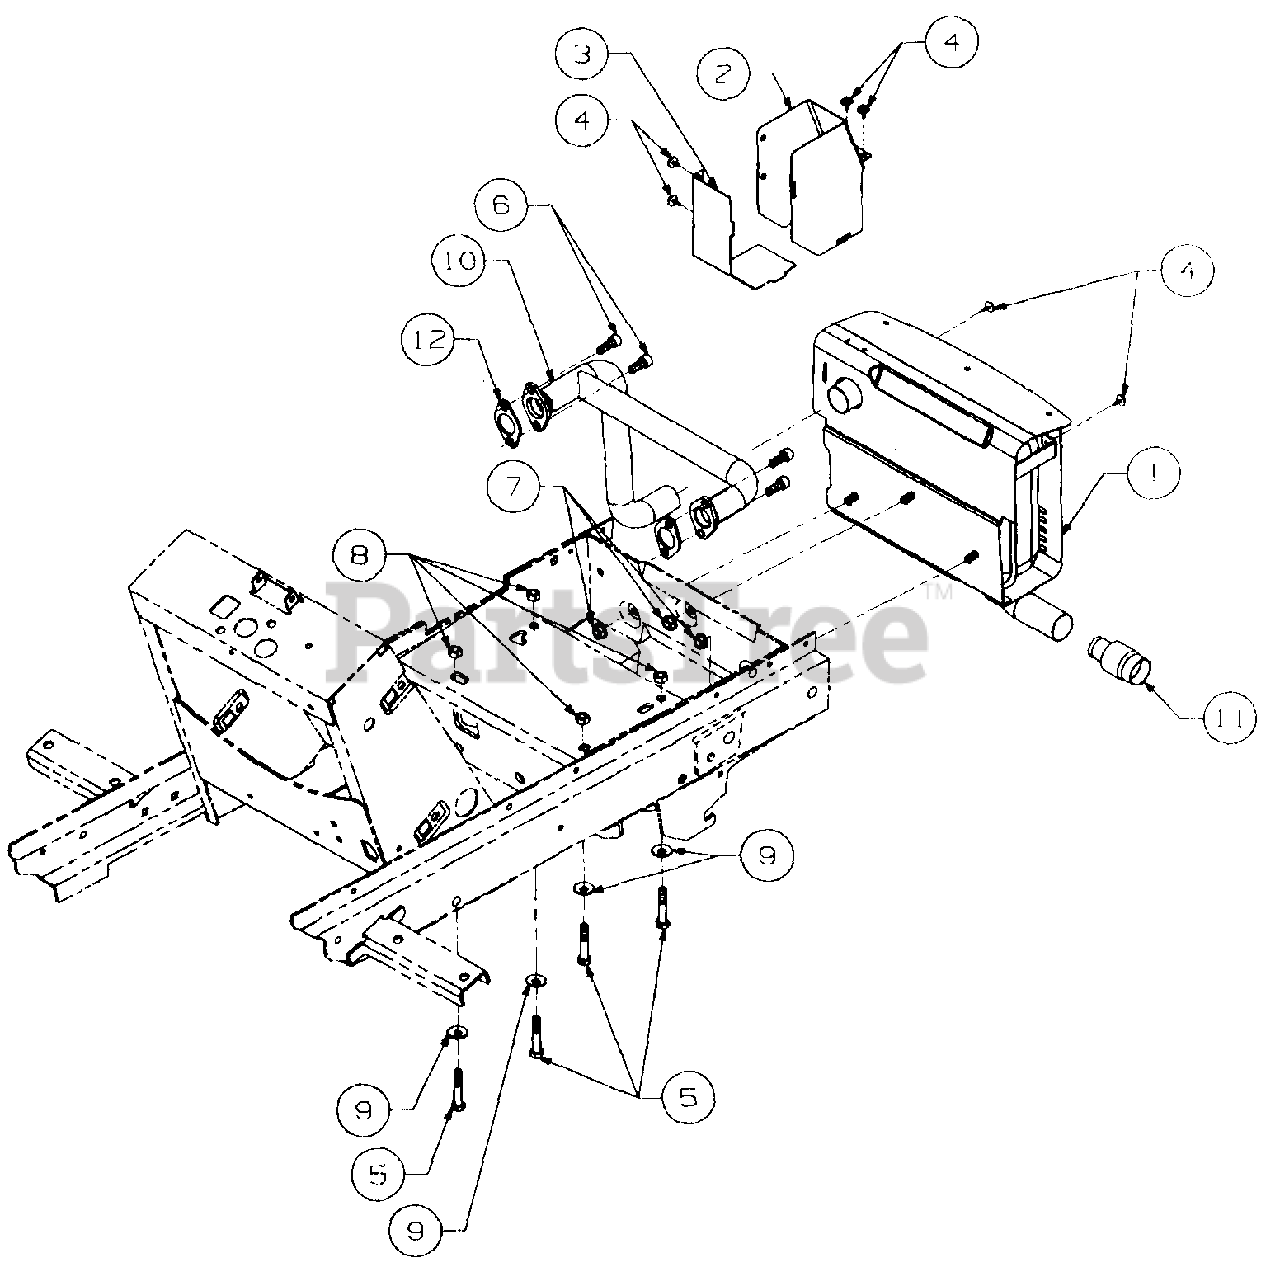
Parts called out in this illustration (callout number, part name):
1	Muffler Assembly
2	Shield, Exhaust Tube Heat
3	Shield, Exhaust Tube Rear
4	Screw, Hex Wash Hd Tapp #10-16 x .38
5	Bolt, Engine Mounting, 5/16-18 x 1.75 GR5
6	Screw, Socket Hd Cap M8-1.25 x 20mm
7	Nut, Hex Flange Lock, 5/16-18
8	Nut, Hex, 5/16-18 GR5
9	Washer, Bell, .345 x .88 x .060
10	Tube, Exhaust
11	Arrestor, Spark
12	Gasket, Exhaust
